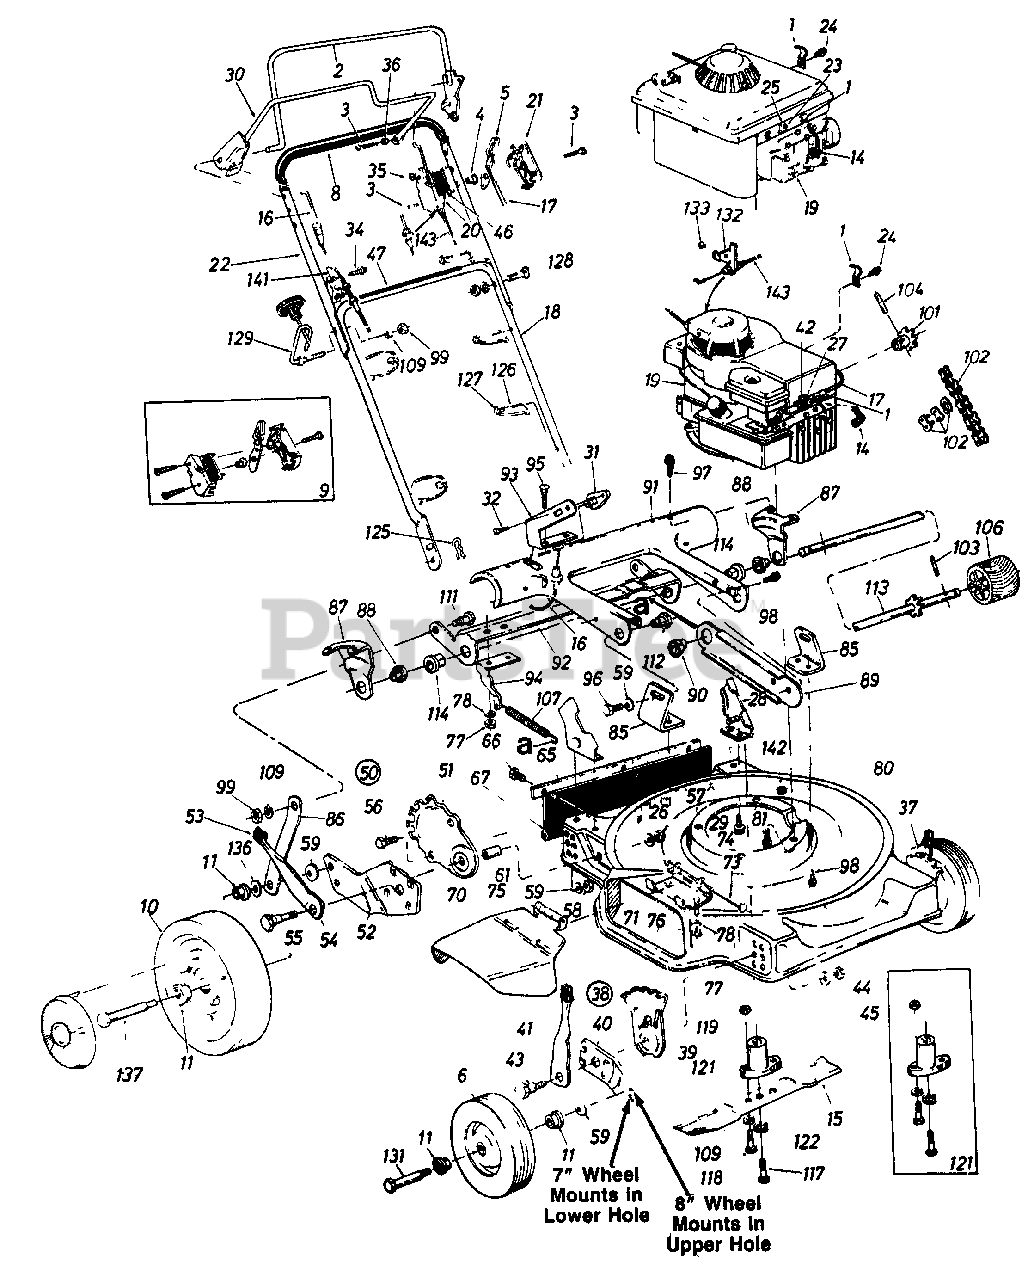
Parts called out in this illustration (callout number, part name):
1	Casing Clamp
2	Control Handle Ass'y. L.H.
3	Truss Mach. Hi-B 0 Tap Scr. #12 x 1.5"
4	Control Disc Pin
5	Throttle Control Lever
6	Front Wheel Ass'y. Comp.
8	Grip
9	Control Housing Comp.
10	Rear Wheel Ass'y Comp.
11	Fl Ball Brg. 1/2" I.D.
14	Spark Plug Insulator
15	22" Blade
16	Clutch Cable w/ Spring 33"
17	Throttle Wire 53"
18	Lower Handle (Chrome)
19	Engine
20	Clutch Panel Half
21	Control Panel Half
22	Upper Handle (Chrome)
23	Hex AB-Tap Scr. #8 x .50"
24	Hex B-Tap Scr. #10 x .38"
25	Casing Clamp
26	Bell-Wash. 5/16" I.D.
27	Hex "B"-Tap Scr. #10 x .38"
28	Handle Brkt. Ass'y L.H.
29	Hex B-Tap Scr. 5/16-18 x .5"
30	S.P. Bail Ass'y.
31	Barrel Cable Hold-Down R.H.
32	B-Tap Scr. #10 x .38 Lg.
34	Hex Wash. AB-Tap Scr. 5/16 x .75"
35	Spr-Wash. .206 I.D. x .448
36	Spacer .23 I.D. x .30 O.D.
37	Front Height Adj. Ass'y. L.H.
38	Front Height Adj. Ass'y. R.H.
39	Height Adj. Plate
40	Pivot Bar
41	Spring Lever Ass'y. w/ Knob
42	Casing Clamp
43	Shld. Bolt .50 Dia. x .430
44	Hex Nut 3/8-16 Thd.*
45	Bell-Wash. .39 I.D. x 1.38 O.D
46	Control Label
47	Instruction Label
50	Rear Height Adj. Ass'y. R.H.
51	Index Plate
52	Pivot Bar R.H.
53	Spring Lever Knob
54	Spring Lever
55	Shld. Bolt .50 Dia. x .433
56	Hex Bolt 3/8-16 x .75
57	Hex Cent. L-Nut 5/16-18 Thd.
58	Hex Nut 3/8-16 Thd.*
59	Bell-Wash. .40 I.D. x .88 O.D.
61	Spacer .383 I.D. x .503 O.D.
65	Retaining Strip
66	Hex AB-Tap Scr. 1/4 X .62
67	Rear Flap Ass'y.
70	Chute Deflector Ass'y.
71	Adapter Plate
74	Push Nut 1/4"
75	Torsion Spring
76	Hex Bolt 1/4-20 x .50 Lg.*
77	Hex Nut 1/4-20 Thd.*
78	L-Wash. 1/4 I.D.*
80	22" Deck Ass'y.
81	Hex TT-Tap Scr. 3/8-16 x 1.0
85	Pivot Brkt.
87	Axle Brkt.
88	Fl. Ball Brg. 1/2" I.D.
89	Brg. Support
90	Fl. Ball Brg. 1/2" I.D.
91	Pinion-Pivot Cover
92	Drive Engagement Cam
93	Engagement Arm L.H.
94	Spring Bracket
95	Carriage Bolt 1/4-20 x .62
96	Hex Bolt 3/8-16 x .50 Lg.*
97	Hex AB-Tap Scr. 1/4 X .62
98	Hex AB-Tap 1/4 X .62"
99	Hex Nut 5/16-18 Thd.*
101	1OT Sprocket Ass'y.
102	#48 Chain 1/2" Pitch 50 Links
103	Spring Pin Spir. 3/16 Dia. x 1.25
104	Spring Pin Spir. 3/16 Dia. x 1.0
106	Drive Pinion
107	Extension Spring 4.25 Lg.
109	L-Wash. 5/16 I.D.*
111	Shld. Bolt .437 Dia. x .162
112	Shld. Nut .625 Dia. x .165
113	Pinion Shaft w/ 7T Sprocket
114	Fl. Ball Brg. .501 I.D.
117	Hex Bolt 3/8-24 x 2.25
118	Hex Bolt 5/16-24 x 1.0 Spec.
119	Hex Nut 5/16-24 Thd.
121	Blade Adapter Kit
122	L-Wash. 3/8 I.D. H.D.
125	Intern. Cot. Pin 5/16 Dia.
127	Cable Anchor
128	Curved Carriage Bolt 5/16-18 x 1.38" Lg.
129	Rope Guide Bolt
131	Front Axle Bolt
132	Cable Bracket
133	Pop Rivet .156" Dia. x .379
136	Fl-Wash. .531 I.D. x .93 O.D.
137	Rear Axle Bolt
141	Cable Brkt.
142	Plastic Plug
143	Control Cable 39" (Green)
8222-000-6	Hardware Pack
